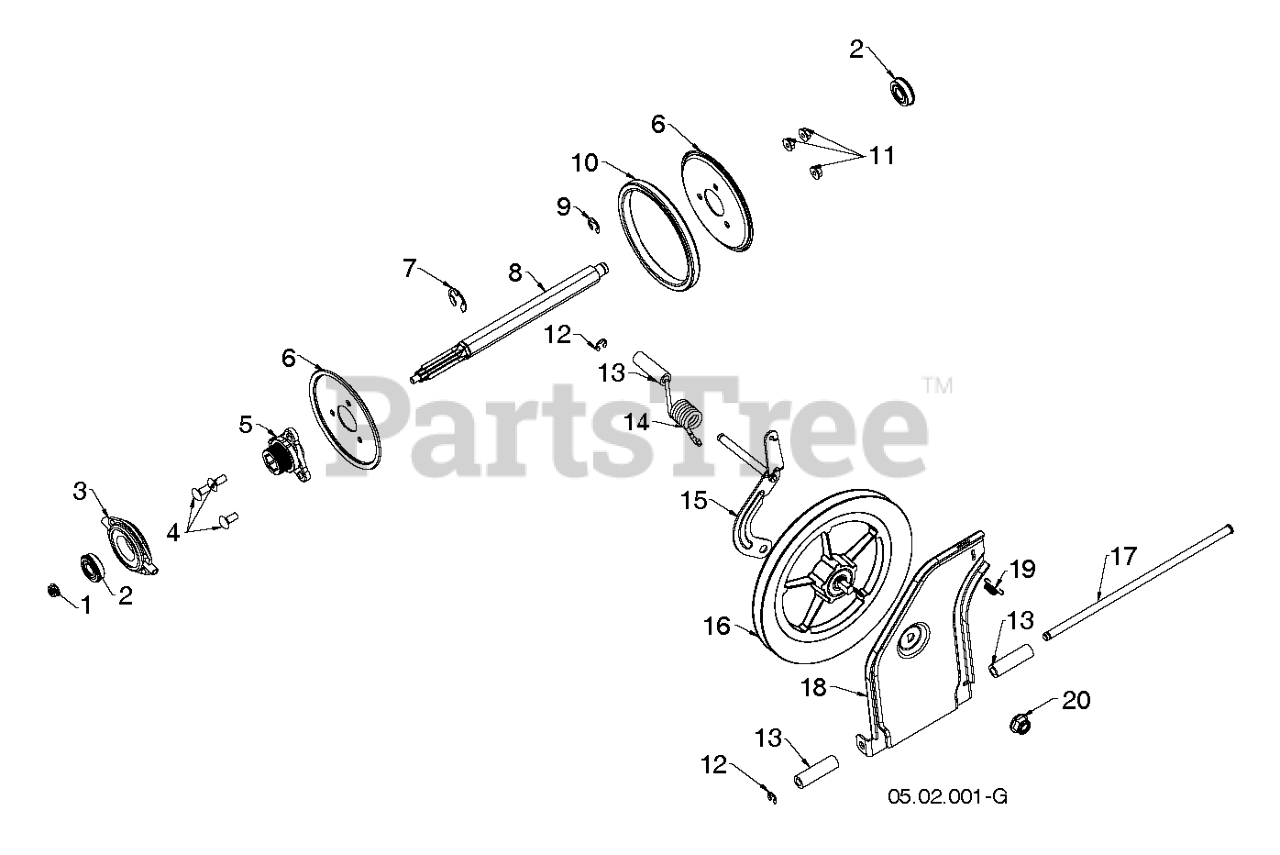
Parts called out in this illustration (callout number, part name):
1	NUT.HEX.FLANGE.LOCK.5/16-18
2	BEARING 9/16 ID. SNR
3	BEARING HOUSING ASSY TRUNNION
4	BOLT.CARR.SQNK.5/16-18UNC.X3/4
5	HUB.RUBBER.WHEEL
6	PLATE.RUBBER.WHEEL.BLACK
8	SHAFT SHAFT,7T REDUCTION
9	RING.RETAINING.1622-2RSNR.CLER
10	RING RUBBER
11	NUT.LOCK.5/16-18
12	RETAINER RING E-RING CLEAR ZI
13	SPACER YOKE, TORSION SPRING
14	SPRING TORSION DRIVE
15	BRACKET.YOKE.ASSEMBLY.479
16	PULLEY.FRICTION.DISC.COMBO
17	ROD ROD,PIVOT, SWING PLATE ROD
18	PLATE.SWING.FRICTION PULLEY.47
19	SPRING LATCH
20	NUT 1/2-13 HEX FLANGE NYLOK CL
